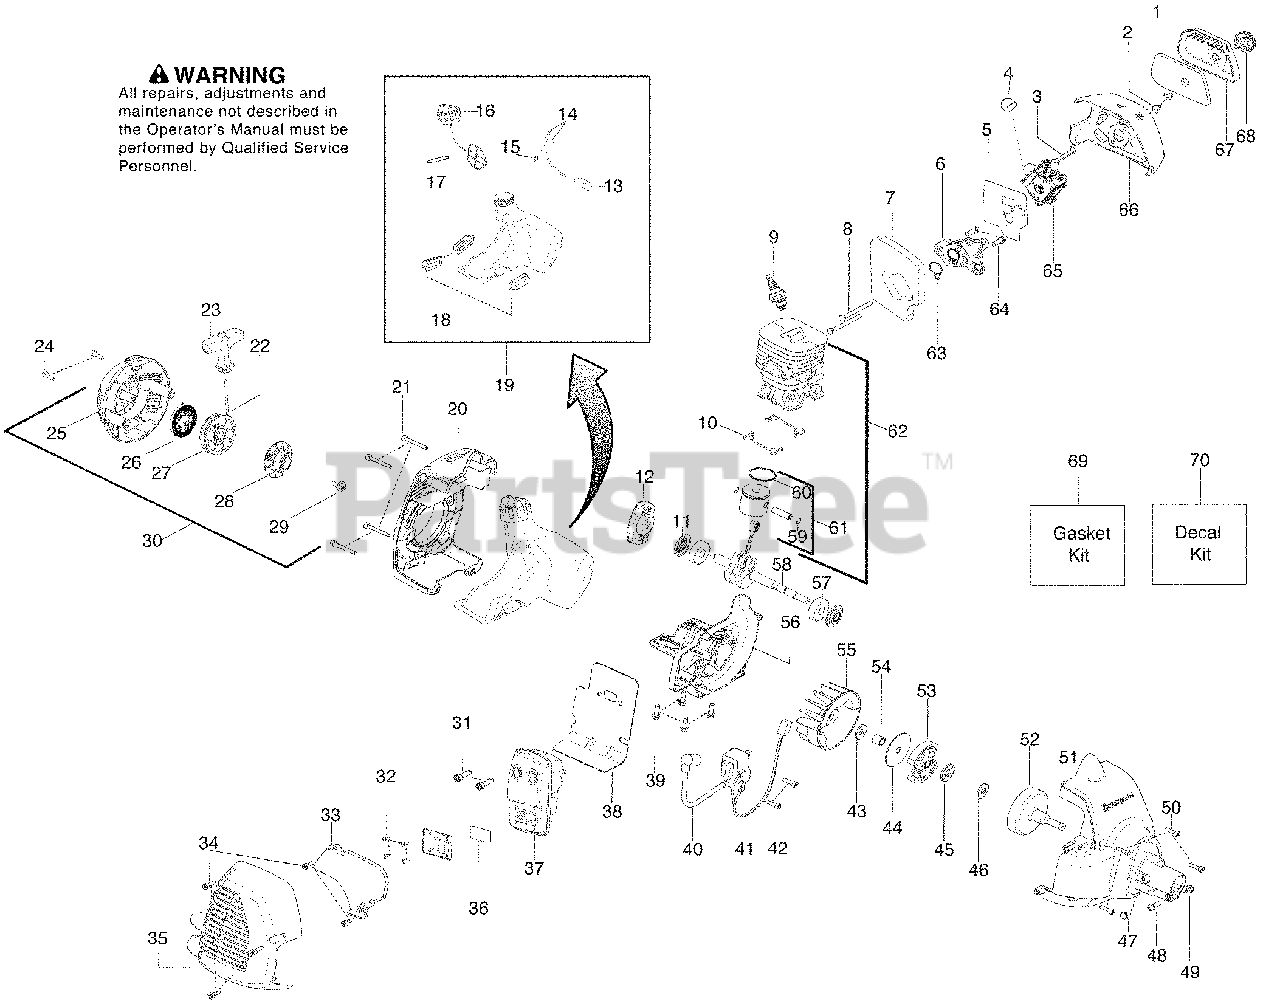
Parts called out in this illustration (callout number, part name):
2	Nut-Carb. Screw
3	Lever - Choke
4	Bulb-Purge
5	Kit-Carb. Gasket
6	Adaptor-Carb.
7	Foam-Gasket
9	Plug-Spark (RCJ-8Y)
10	Seal-Cylinder
11	Seal-Crankshaft
12	Assy-Starter Pawl
13	Assy-Fuel Filter
14	Kit-Fuel Line
15	Fitting-Fuel line
16	Assy-Cap w/ret.
17	O-ring - Fuel Cap
18	Isolator-Fuel Tank
19	Kit-Fuel Tank Assy.
20	Shroud-Rear
22	Kit-Rope
23	Handle-Starter
25	Hsg.-Starter w/eyelet
26	Kit-Starter Spring
27	Kit-Starter Pulley
28	Pulley-Driver
30	Assy-Starter Hsg.
31	Bolt-Muffler
32	Screw
33	Shield-Heat
35	Guard-Muffler
36	Kit-Spark
37	Assy-Muffler
38	Gasket-Paper Met.
41	Assy-Leadwire
44	Washer-Clutch
45	Bearing - Thrust
46	Washer - Thrust
51	Assy-Fan Housing
52	Assy-Clutch Drum
53	Kit-Clutch Assy.
56	Crankcase-Cast
58	Assy-Crankshaft
59	Retainer-Piston Pin
60	Ring-Piston
61	Kit-Piston
62	Kit-Piston/Cyl.
63	Seal-adaptor
65	Kit-Carb.
66	Airbox
67	Cover-Air Box
69	Kit-Gasket
